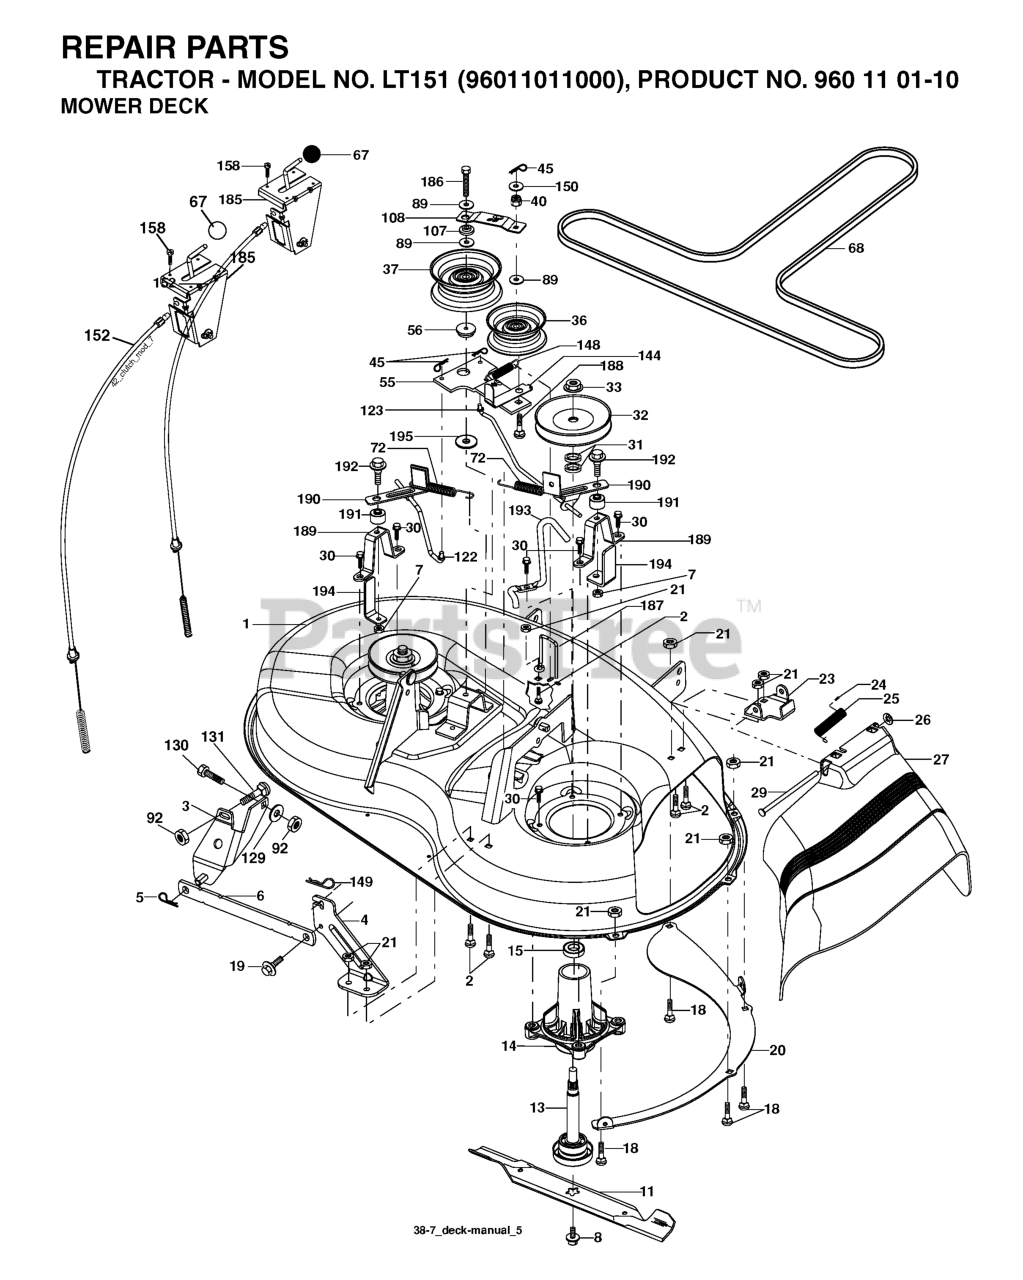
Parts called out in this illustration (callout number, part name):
1	DECK SVCX1 38/94 192556X431
2	RP BOLT 5/16-18 X3/4 ZN/YEL GR
3	BRKT ASM SWAY BAR
4	BRACKET DECK SWAY BAR 38"/42"
5	RETAINER-SPRNG RB
6	BAR SWAY DECK
7	NUT.71038.31-18.HEX.NYLOCK
8	BOLT.WASHER.ASM.7/16-2
11	BLADE 38" PREMIUM
13	SHAFT.ASM.MDRL.N/GREASE.38
14	RP.HOUSING.MANDREL.4PT.
18	BOLT
19	BOLT SHD 5/16-18
20	BAFFLE.VORTEX.FRONT.38"
21	LOCKNUT
23	BRKT.DEFLECTOR.38"2005+
24	CAP-SLEEVE LT
25	SPRING.TORSION.DEFLECT
26	NUT PUSH M
27	SHIELD.DEFLECTOR.MWR.38-7/97CM
29	ROD.HINGE
30	SCREW, WASHER HEAD
31	WASHER.SPACER.MANDREL
32	PULLEY MANDREL
33	NUT.FLANGE.LOCK.TOP
36	FLAT IDLER PULLEY
37	PULLEY.IDLER.FLAT.UNPLATED
45	RETAINER M
56	SPACER.RETAINER.MOWER
67	KNOB T (3/8 HOLE)
68	V-BELT.MOWER.38"2005+
72	SPRING.BRAKE.RETURN.38"
89	WASHER
92	NUT
107	SPACER.IDLER.ARM
108	STIFFENER.IDLER.ARM
122	LINKAGE.BRAKE.LH.38"
123	LINKAGE.BRAKE.RH.38"
129	WASHER
131	BOLT D
144	KEEPER BELT
148	IDLER RETURN SPRING
149	SPRING.RETAINER.YELLOW.ZINC
152	CABLE.CLUTCH.38".SERVICE
158	SCREW
185	HEAD ASM. CABLE CLUTCH
186	SCREW.HXWSH.3/8
187	KEEPER BELT
188	BOLT, CARRIAGE IDLER
189	STAND, BRAKE
190	ARM, BRAKE
191	BRAKE.SPACER.38".DECK
192	BOLT/WASHER ASM 5/16-18
193	KEEPER BELT RH MANDREL
194	GUARD BRAKE
195	WASHER 12/32X2X10GA
